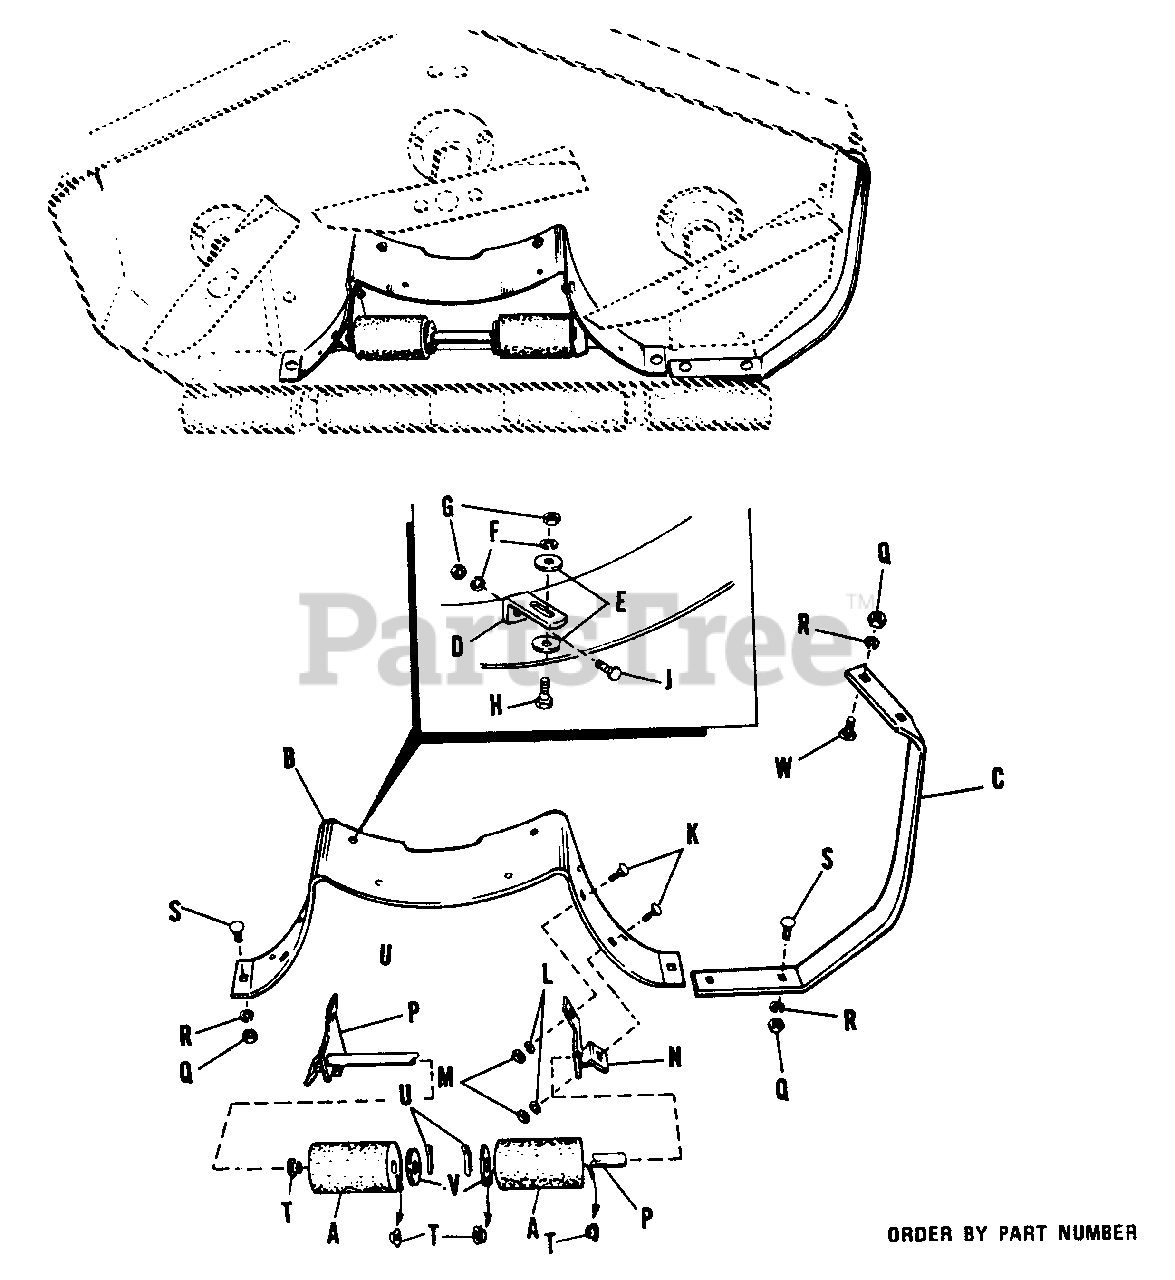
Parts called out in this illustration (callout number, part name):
A	Roller W/Bushing
C	Guard Assembly, Housing
D	Clip Baffle
E	Washer, Plain, 1/4"
F	Washer, Lock, 1/4"
G	Nut, Hex, Full, 1/4"-20 NC
H	Capscrew, Hex, 1/4"-20 x 5/8" lg.
J	Screw, Recessed Hex, Self-Tapping 1/4"-20 NC x 7/8" lg.
K	Bolt, Carriage, 5/16"-18 NC x 3/4" lg.
L	Washer, Lock 5/16"
M	Nut, Hex, Full, 5/16"-18 NC
N	Bracket, Roller, Lower, L.H.
P	Bracket & Shaft Assembly
Q	Nut, Hex, Full, 3/8"-16 NC
R	Washer, Lock, 3/8"
S	Bolt, Carriage, 3/8"-16 NC x 3/4" lg.
U	Pin, Cotter, 3/16" x 1" lg.
W	Bolt, Carriage, 3/8"-16 NC x 1" lg.
